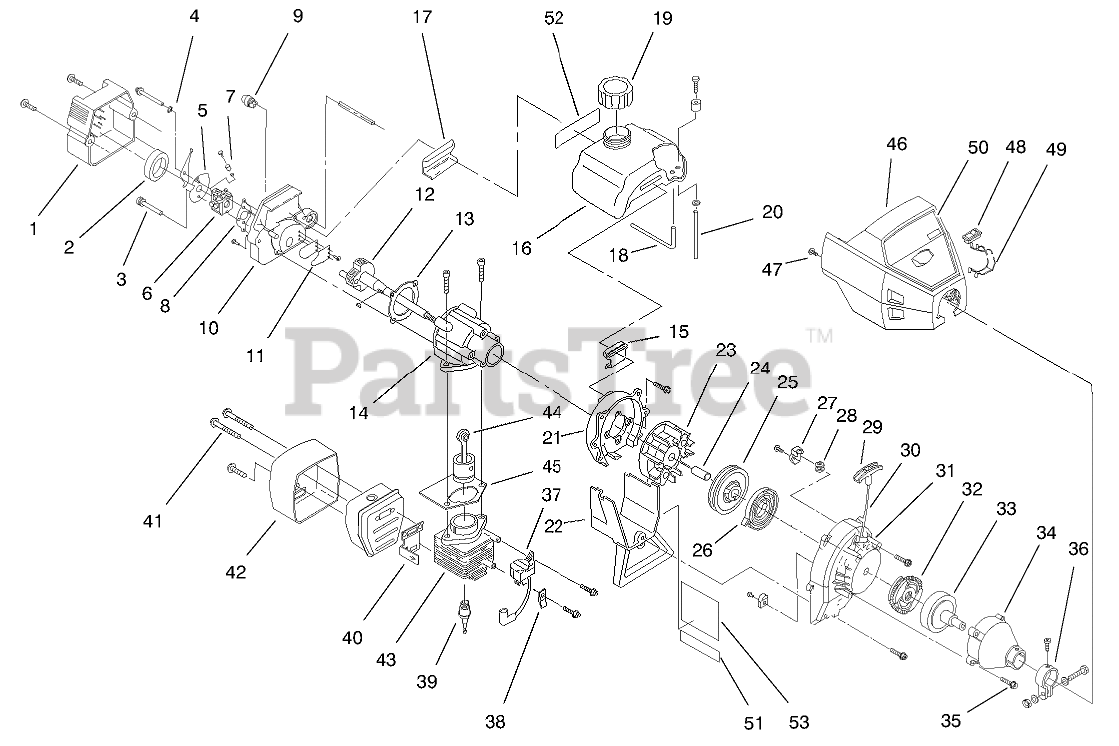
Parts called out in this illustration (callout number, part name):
1	Carburetor/Air Cleaner Asm. (Incl. Ref. #2)
2	FILTER - AIR CLEANER
3	ASSEMBLY - MOUNTING BOLT
4	WASHER - WAVEY
5	LEVER - CHOKE & PLATE
6	Carburetor Asm.
7	THROTTLE ADJ ASM
7	ASM - THROTTLE ADJUSTMENT
8	CARBURETOR GASKET(10 PER PACK)
9	PRIMER & HOSE ASM
10	Carburetor Mount Asm.
11	ASSEMBLY - REED
12	ASM - POWER SHAFT
13	CARB MT GASKET (10-PK)
14	Crankcase Service Asm. (Incl. Ref. #12)
15	FRONT MOUNTING PAD
16	Fuel Tank Asm. (Incl. Ref. #18-20)
17	REAR MOUNTING PAD
18	ASSEMBLY - RETURN LINE
19	FUEL TANK CAP
20	FUEL LINE ASM
21	SHROUD ASM
22	Shroud Extension & Stand
23	FLYWHEEL
24	SPACER
25	RECOIL PULLEY ASM
26	RECOIL SPRING
27	PULLEY RETAINER ASM
28	ROPE GUIDE
29	Handle-Pull
31	ASSEMBLY - STARTER HSG
32	Clutch Rotor Asm.
33	CLUTCH DRUM ASM
34	Clutch Cover Asm.
35	CLUTCH COVER SCREW ASM
36	CLAMP ASM - UPPER
37	Module Asm.
38	GROUND TAB
39	SPARK PLUG
40	GASKET - EXHAUST
41	ASM - MUFFLER MTG BOLT
42	Muffler Asm. (Incl. Ref. #41)
43	ASSEMBLY - CYLINDER
44	PISTON & ROD ASM
45	CYLINDER GASKET
46	COVER - ENGINE
47	Screw
48	SWITCH ASM
49	LEAD WIRE ASM
50	DECAL - TORO
51	Decal-Warning
52	Decal-Fuel & Oil Mix
52	DECAL - CARBURETOR
